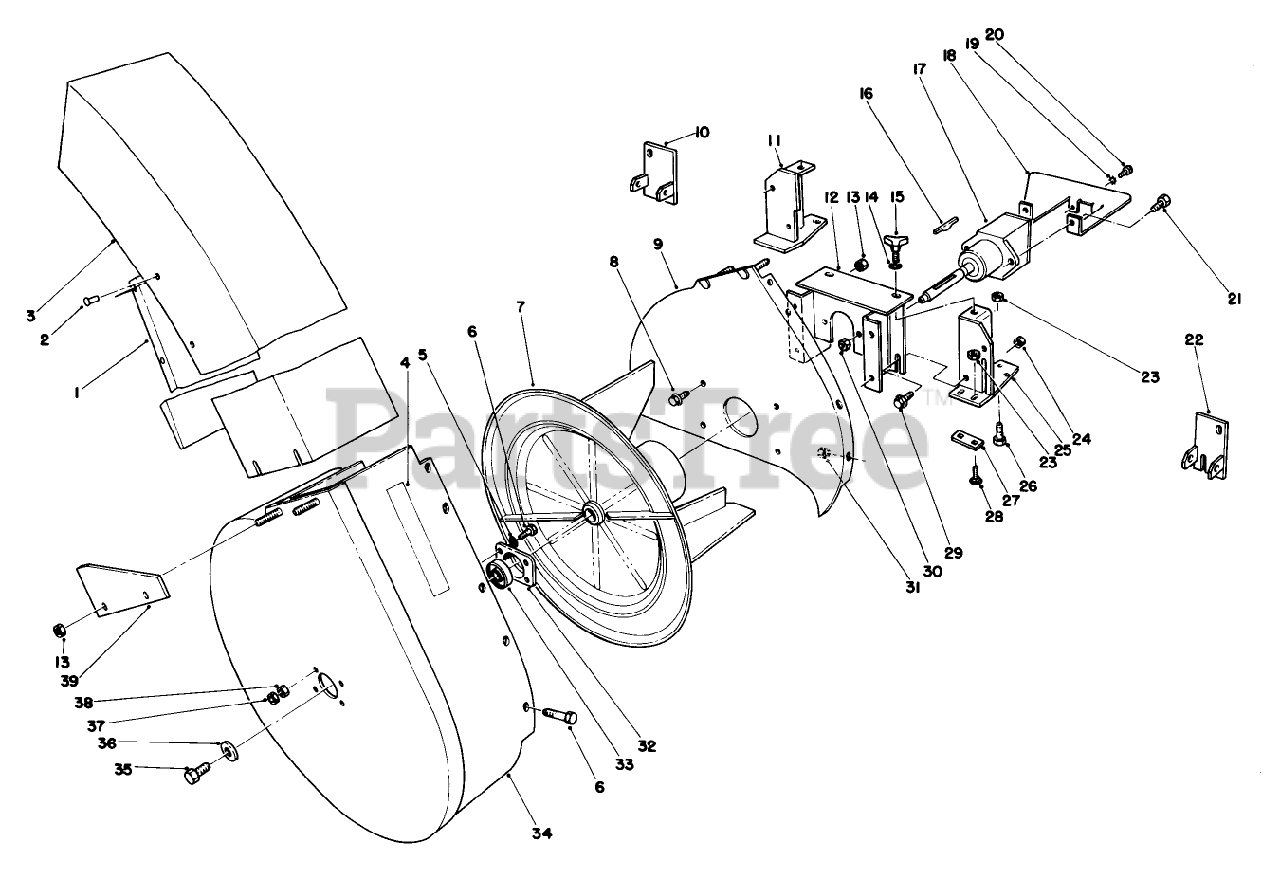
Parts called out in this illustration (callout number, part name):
1	Deflector
3	Chute Assembly (Incl. Ref. #1 & 2)
4	Decal-Waming
5	WASHER-LOCK
6	SCREW-HH
7	Impeller
8	SCREW-HHF
9	Mounting Plate
10	Bracket-Deflector L.H.
11	LH BRACKET ASM
12	Blower Mount
13	NUT-LOCK, NI
14	WASHER-FLAT
17	Asm-Gear Box
18	Cover-Gear Box
19	WASHER-LOCK, EXT
21	SCREW-HH
22	Bracket-Deflector R.H.
23	NUT-LOCK, CONE
24	NUT-JAM
25	RH BRACKET ASM
26	SCREW-HH
27	Plate-Bracket
28	BOLT-CARR
29	SCREW-HHF
30	NUT-LOCK, NI
31	NUT-LOCK, NI
32	CUP-BEARING
33	BEARING-BALL
34	Blower Housing
35	CAPSCREW 3/8 16 3/4
36	SPACER
37	NUT-JAM
38	NUT-HEX
39	Bracket
